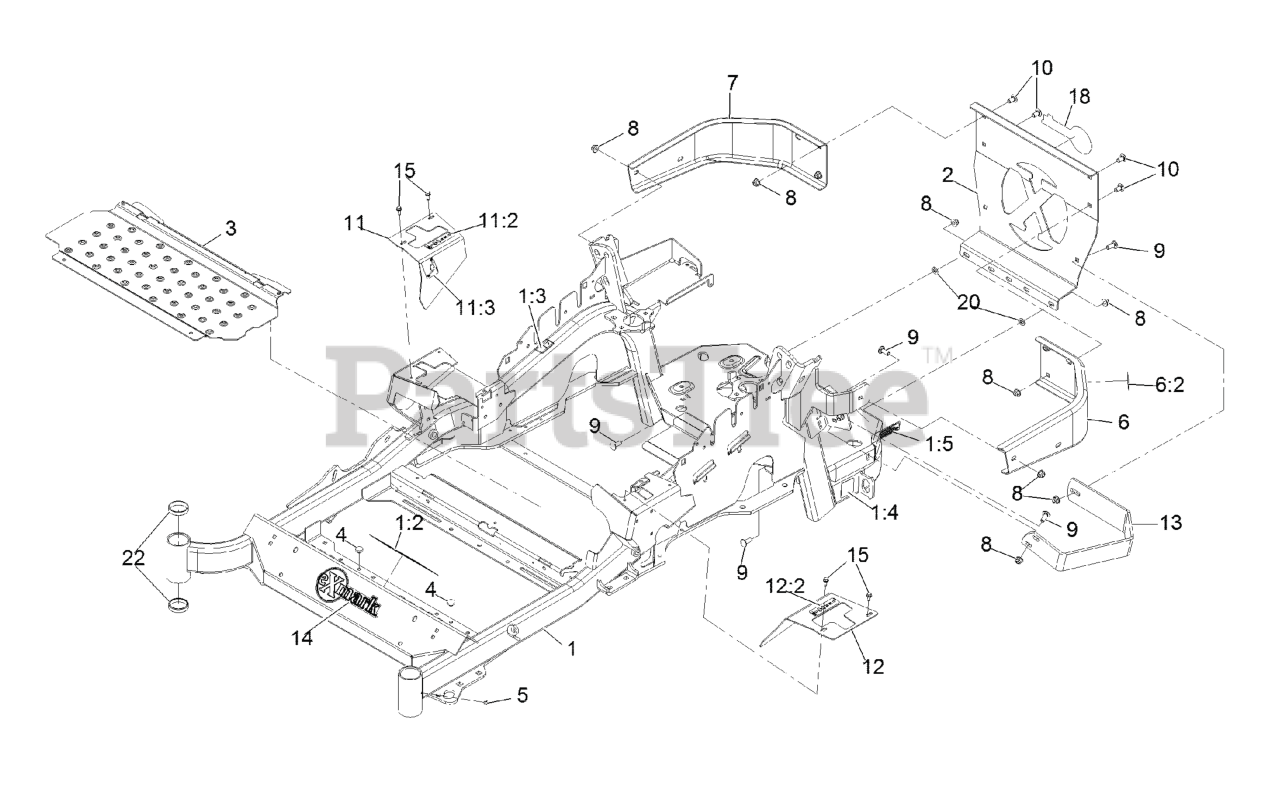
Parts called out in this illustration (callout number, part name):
1	MAINFRAME ASM
1:2	DECAL-DANGER
1:3	DECAL-WARNING
1:4	DECAL-HAZARD, PINCHED FINGER
1:5	DECAL-ARRESTOR, SPARK
2	PLATE,REAR GUARD
6	LH BUMPER ASM
6:2	DECAL-WARNING
7	BUMPER-RH
8	NUT-HF, NI
9	SCREW-CARR
10	SCREW-CARR
11	RH MOTION CONTROL COVER ASM
11:2	DECAL-CONTROL, MOTION
11:3	DECAL-PARK BRAKE, CE
12	LH MOTION CONTROL COVER ASM
12:2	DECAL-CONTROL, MOTION
13	GUARD-MUFFLER
14	DECAL-EXMARK
15	SCREW-HWH
20	NUT-PUSH
22	CUP-BEARING
